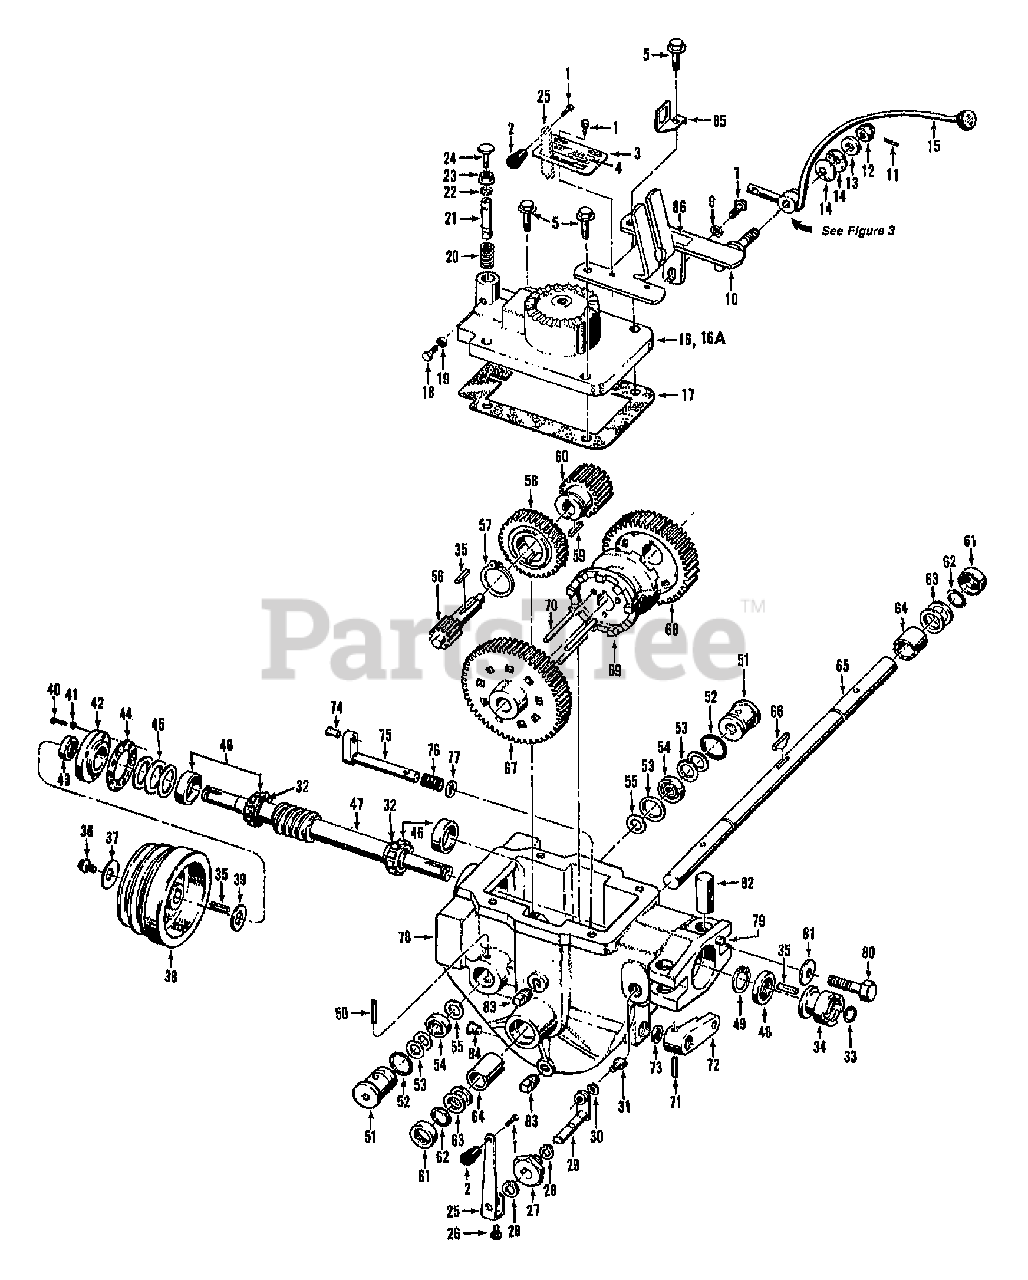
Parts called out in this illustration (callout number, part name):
1	SCR 10-32
2	KNOB-TAPERED
3	PLATE-TINE ENGAGE W/DECAL #2599 (#4)
4	DECAL-TINE ENGAGE
5	SCR-HFLK 3/8-16X1.50
6	THIS REF. NOT USED
7	SCR-HFLK 5/16-18X.75 ZP
8	THIS REF. NOT USED
9	WASHER-FLAT 5/16 SAE
10	BRKT-H HOOD 2149 (SEE #86 FOR DECAL)
11	PIN-SPRING .125 X 1
12	NUT-HEX 1/2-20
13	WASHER-# SHOULDER ZP (SHLDR FACES DISC WSHRS)
14	WASHER-# 1.97X1X.118
15	LEVER, WHEEL SPEED SHIFT (SHOWN FOR REF ONLY)
16	COVER-TRANS RED
16A	ASSM-TRANS COVER OPC (INCL #'S 18-24)
17	GASKET-TRANS COVER
18	SCR-HH 5/16-18X1.0 G5 ZP (REMOVE WITH CARE)
19	NUT-HEX 5/16-18 ZP
20	SPRING-REV PLUNGER ZP (REMOVE WITH CARE)
21	ASSM-NEUTRAL PLUNGER W/ CLIP RING #22 (9504)
22	RING-KLIP EXT .594 ID ZP
23	NUT-HFLK 3/8-16 ZP
24	SCR 3/8-16X1.5 UNC-2AG
25	LEVER-ECCENTRIC RED (ALSO SEE REF #'S 1-4)
26	SCR-HH 1/4-20X.5 GR5 YEL
27	BUSHING-.87X.5X.62 ECC
28	RING-RETAINING 5100-50
29	KIT-CLUTCH DOGS TILLER
30	WASHER-LK .25 HI-COLLAR
31	SCR-HXSKT 1/4-20X.38 G8
32	WASHER-#1.25X.75X.06 (DRIVE SHAFT)
33	RING-RETAIN EXT .707 ID (SNAP RING)
34	KIT-CLUTCH DOGS TILLER (POWER UNIT)
35	KEY-.188 SQX1.0 (USED ON DRVE & PINION SHFTS)
36	SCR-HH 5/16-24X.75 G5 ZP
37	WASHER-.827X.331X.098 (CONCAVE)
38	PULLEY-TRANS MACH
39	WASHER-SHLDR HARDENED
40	SCR-HH 1/4-20X.75 G5 ZP
41	WASHER-LK .25 ZP
42	COVER-FRONT
43	SEAL-PINION SHAFT PT/85030/00
44	GASKET-BRG COVER
45	SHIM-1.75X1.5X.01
45	SHIM-1.75X1.5X.03
45	SHIM-1.75X1.5X.005
45	SHIM-1.75X1.5X.062
46	KIT-BRG CONE&RACE-DRIVESHAFT
47	KIT-TRANS DRSHAFT HORSE (MAIN DRVE, PWR UNIT)
48	SEAL-OIL DRIVESHAFT REAR
49	RING-RETAINING 5000-181 (SNAP RING)
50	PIN-SPIROL .25 X 2.0 (RETAINS #51 1060A PLUG)
51	PLUG-PINION BRG W/RING #52 (9604)
52	RING-O 1 ID
53	SHIM-1.234X1.015X.033
53	SHIM-1.234X1.015X.062
53	SHIM-1.234X1.015X.01
54	BRG-BALL (7 BALLS)
55	WASHER-# 1X.484X.06 (1 USED ON LT & RT SIDES)
56	GEAR-SPLINE 10 TEETH MACH
57	RING-RETAINING 5100-150 (SNAP RING)
58	GEAR-WORM 36 TEETH MACH
60	GEAR-SPUR 20 TEETH MACH
61	SEAL-OIL WHEELSHAFT
62	RING-HEAVY EXT .906 ID (SNAP RING)
63	SHIM-1.375X1.015X.062
63	SHIM-1.375X1.015X.03
63	SHIM-1.375X1.015X.015
63	SHIM-1.375X1.015X.01
63	SHIM-1.375X1.015X.005
64	BUSHING-1.25X1.005X1.5
65	KIT-WHEELSHAFT (INCL 66 & 62)
66	KEY-HI PRO .25X1.812
67	GEAR-SPUR 56 TEETH MACH
68	GEAR-SPUR 46 TEETH MACH
69	CLUTCH-MACH
70	PIN-CLUTCH .25 2.65
71	PIN-SPIROL .188 X 1.25
72	LEVER-ECC. #1029
73	SEAL-OIL ECCENTRIC
74	PIN-.375 X .72
75	SHAFT-ECCENTRIC HORSE TLR
76	SPRING .845 X 1.25
77	WASHER # .875 X .65 X .06
78	CASE-TRANS W/PIN
79	PIN-DRIVE .375X.75 ZP
80	SCR-HH 1/2-13X2.0 G5 ZP
81	WASHER-DISC SPRING (CONCAVE)
82	POST (TC)
83	PLUG-PIPE 1/4 NPT (OIL DRAIN & LVL CHCK PLUG)
84	PLUG-CAP (RED)
85	CLIP-CONNECTOR
86	DECAL-FWD INTERLOCK WIRE
